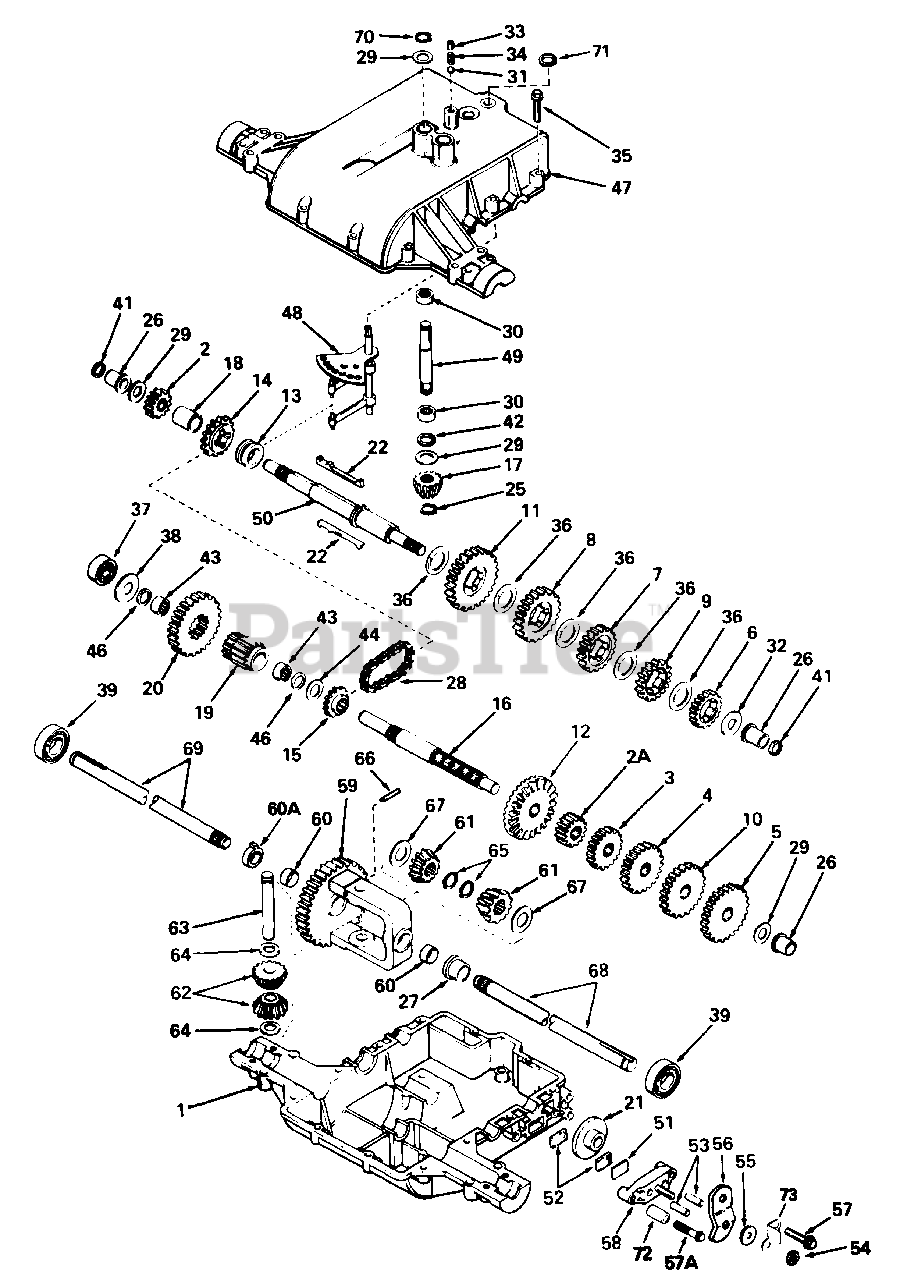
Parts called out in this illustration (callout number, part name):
1	CASE, Transaxle
2	GEAR, Spur (15 teeth)
2A	GEAR, Spur (12 teeth)
3	GEAR, Spur (20 teeth)
4	GEAR, Spur (25 teeth)
5	GEAR, Spur (30 teeth)
6	GEAR, Spur (20 teeth)
7	GEAR, Spur (25 teeth)
8	GEAR, Spur (30 teeth)
9	GEAR, Spur (22 teeth)
10	GEAR, Spur (28 teeth)
11	GEAR, Spur (37 teeth)
12	GEAR, Spur (42 teeth)
13	COLLAR, Shift
14	SPROCKET (14 teeth)
15	SPROCKET (10 teeth)
16	SHAFT, Counter
17	BEVEL PINION, Input
19	PINION, Output
20	GEAR, Output
21	DISK, Brake
25	RING, Retaining
26	BUSHING, Flanged
27	BUSHING, Flanged
28	CHAIN, Roller (No. 41 chain, 22 links)
29	WASHER, Thrust
30	BEARING, Needle
31	BALL, Steel
32	WASHER, Thrust
33	SCREW, Set, 3/8-16 x 3/8
35	SCREW, Hex Hd., Thread Forming, 1/4-20 x 1-1/4
36	WASHER, Thrust
37	BEARING, Ball
38	WASHER, Flat
39	BEARING, Ball
41	SEAL Square Cut
42	SEAL, Square Cut
43	BEARING, Needle
44	WASHER, Flat
46	SEAT, Square Cut
47	COVER, Transaxle
48	ROD & FORK ASSY., Shift
49	SHAFT, Input
50	SHAFT, Brake
51	PLATE, Brake Pad
52	PAD, Brake
53	PIN, Dowel
54	LOCKNUT, 5/16-24
55	WASHER, Flat
56	LEVER, Brake
57	SCREW, Hex Hd. Thd. Form., 1/4-20 x 1-1/4
57A	SCREW, Hex Hd., Thd. Form., 1/4-20 x 2-1/4
58	HOLDER, Brake Pad
59	GEAR ASSY., Differential (Incl. 2 of No. 60)
61	GEAR, Bevel
62	PINION, Bevel
63	PIN, Drive
64	WASHER, Thrust
65	RING, Retaining
66	PIN, Roll
67	WASHER, Thrust
68	AXLE (15-1/2" long)
69	AXLE (12-1/2" long)
70	RING, Retaining
71	SEAL, Square Cut
